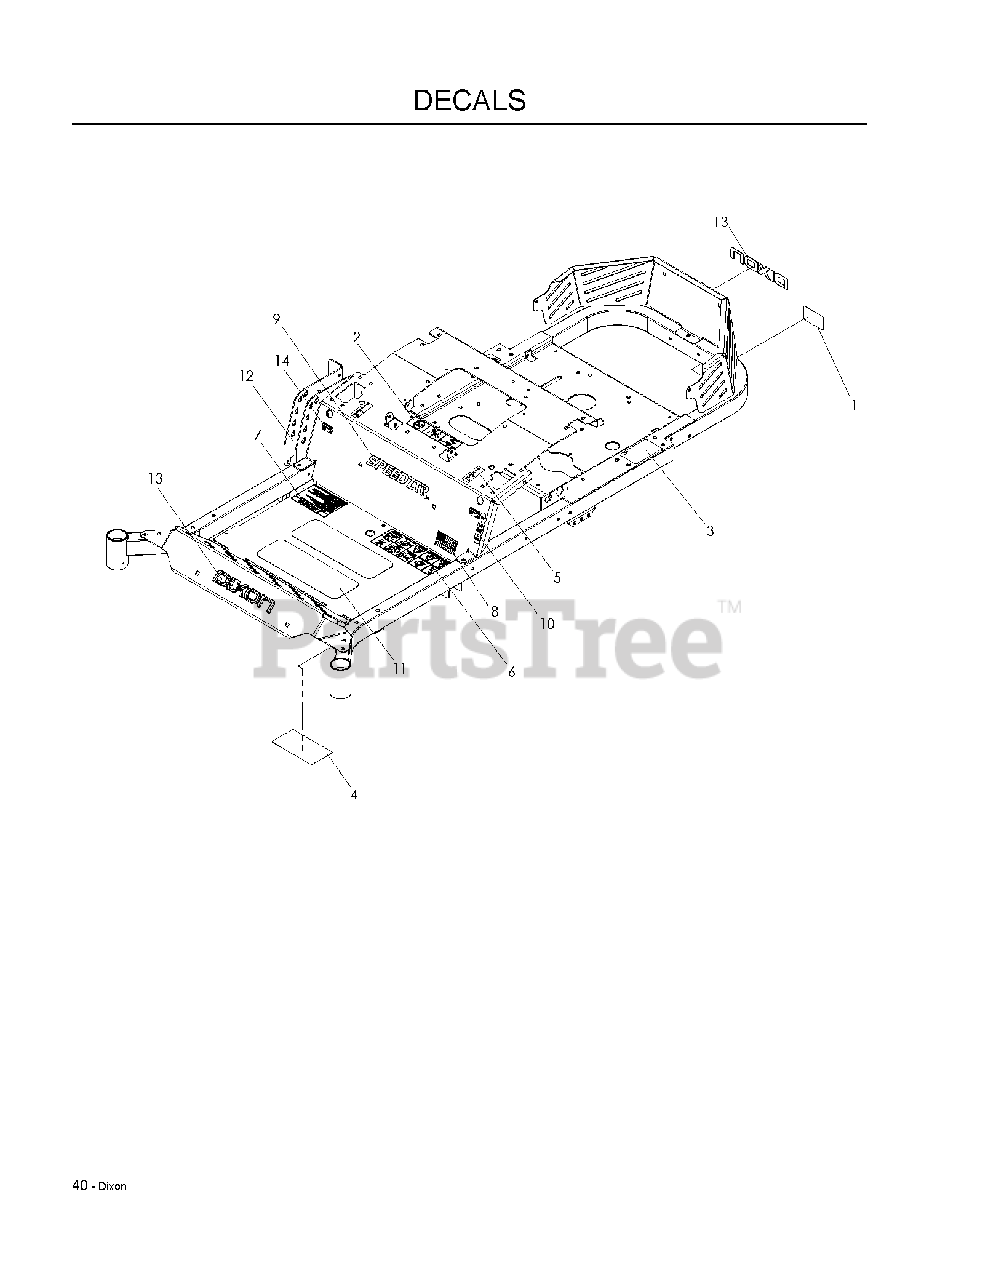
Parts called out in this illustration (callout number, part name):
1	DECAL, PROP. 65
2	DECAL, BATTERY
3	DECAL, DO NOT MOUNT
4	DECAL, SERVICE
5	DECAL, MOTION CONTROL
6	DECAL, SAFETY WARNING
7	DECAL, WARNING
8	DECAL, FLAG
9	DECAL, SPEEDZTR, 8"
10	DECAL, PARK BRAKE
11	ANTI-SKID PAD
12	DECAL, HEIGHT
13	DECAL, DIXON LOGO, DOMED
14	DECAL, F.S.T.
